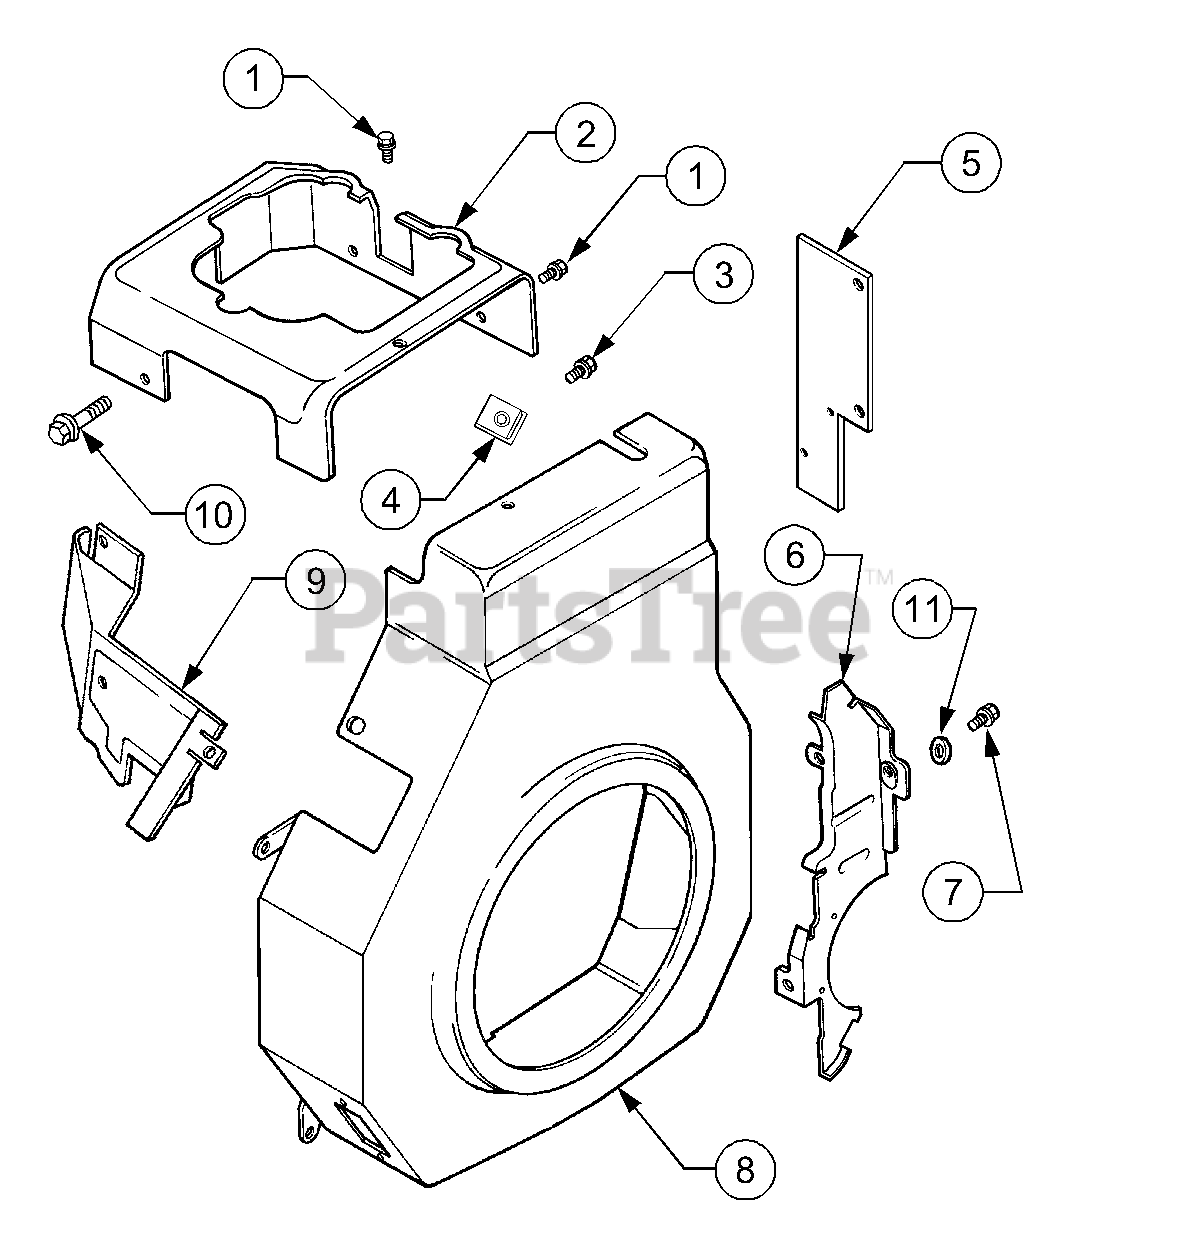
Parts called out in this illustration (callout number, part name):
1	Screw, Hex Flange, M5 x .8 x 10
2	Baffle, Cylinder Head
3	Screw, Hex Flange, M5 x .8 x 16
4	Clip, Mounting
5	Baffle, Cylinder
6	Plate, Blower Housing
7	Screw, w/Washer M5 x .8 x 20
8	Housing, Blower
9	Baffle, Intake Side
10	Screw, Hex Flange, M5 x 0.8 x 10
11	Washer, Plain 1/4"
